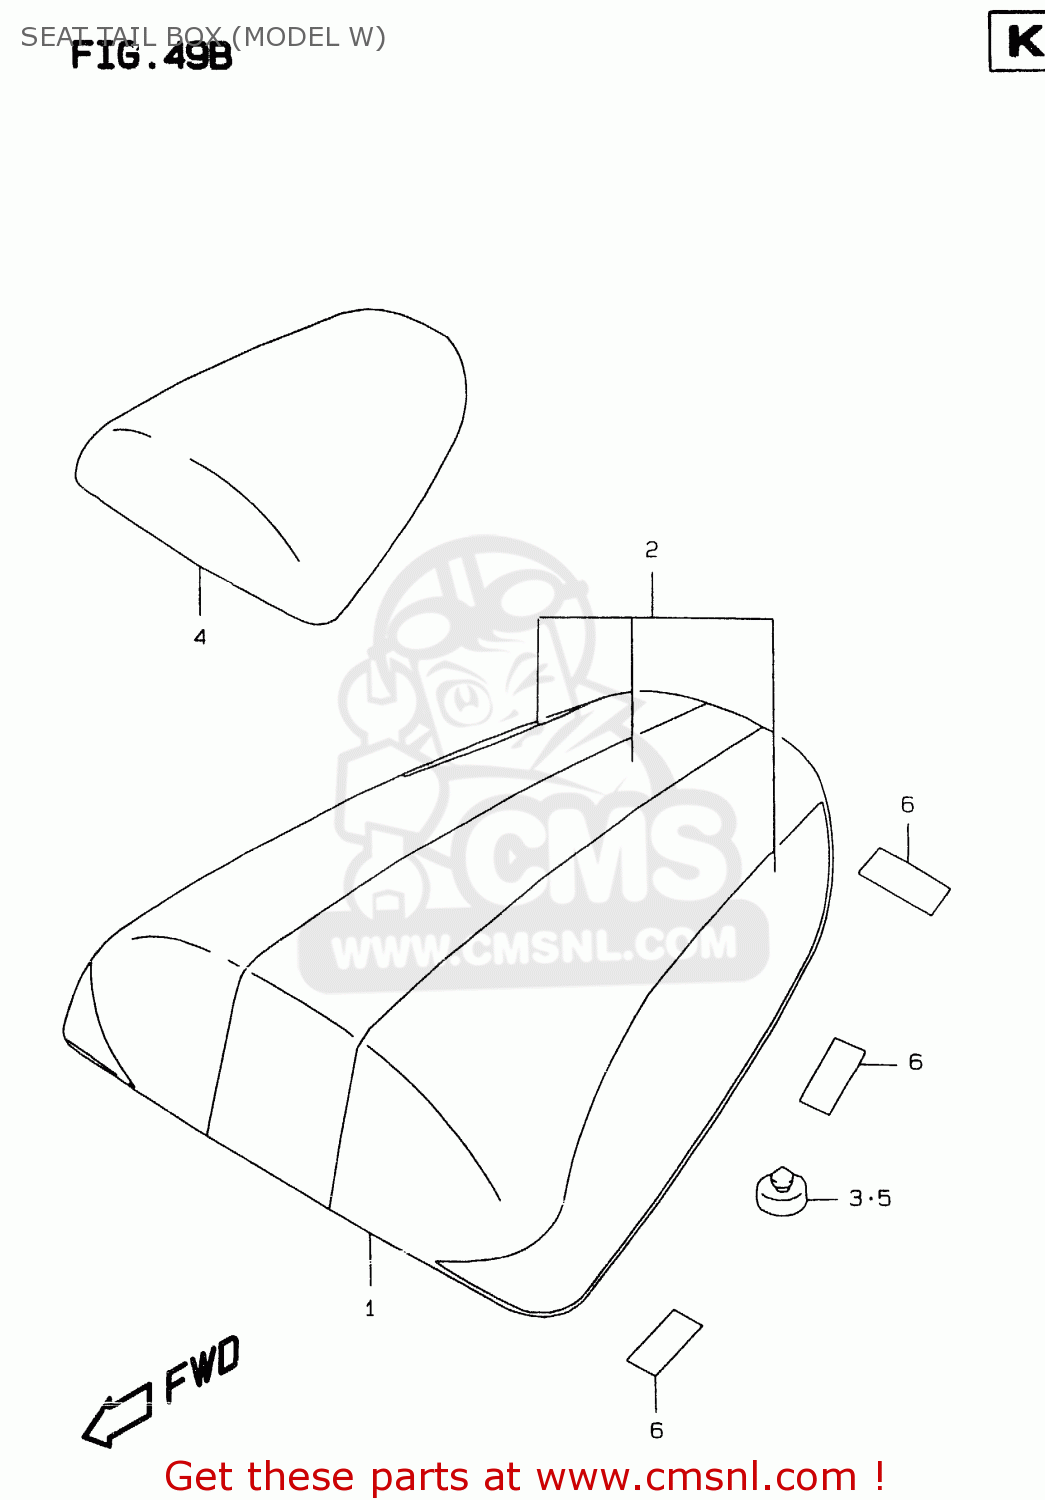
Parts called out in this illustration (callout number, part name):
1	BOX ASSY,SEAT TAIL(BLUE)
2	TAPE SET,BOX SEAT TAIL(WHITE)
3	CUSHION(11.5X22X20)
4	BOX,SEAT TAIL (BLACK)
5	CUSHION(11.5X22X20)
6	PROTECTOR SET,SEAT TAIL BOX
